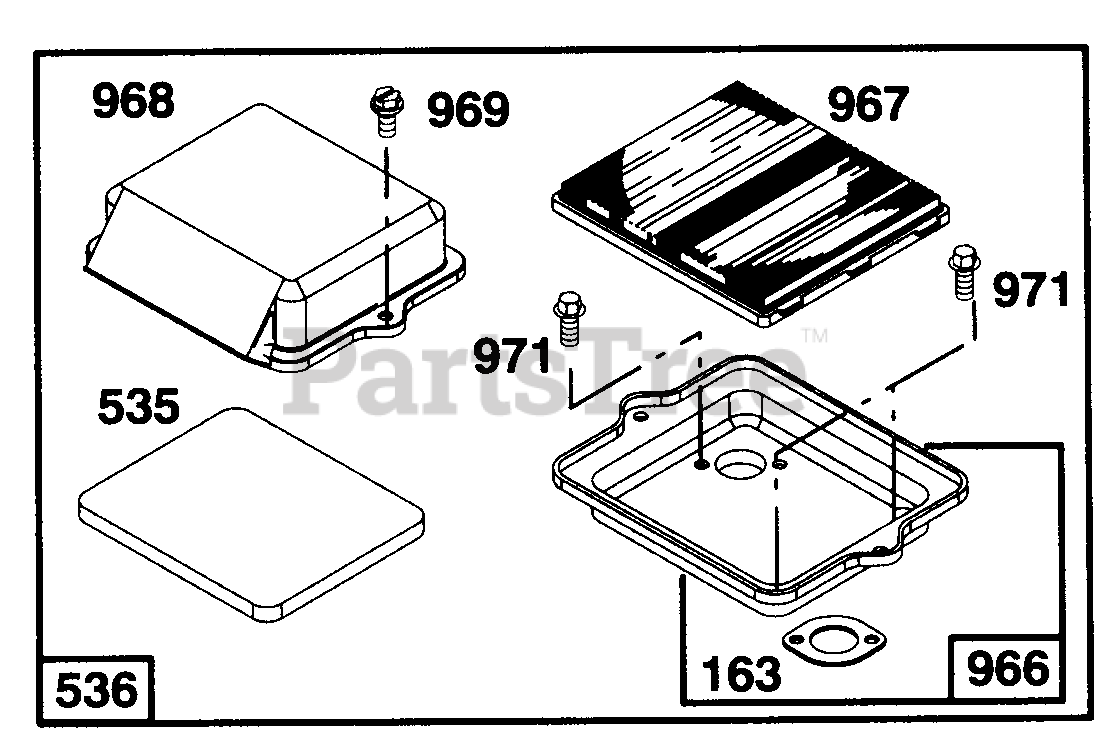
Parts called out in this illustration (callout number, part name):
163	Gasket--Air Cleaner Mounting
535	Element--Air Cleaner
536	Cleaner--Air
966	Base--Air Cleaner
967	Filter--Air Cleaner
968	Cover--Air Cleaner
969	Screw--Air Cleaner
971	Screw--Hex Hd.
